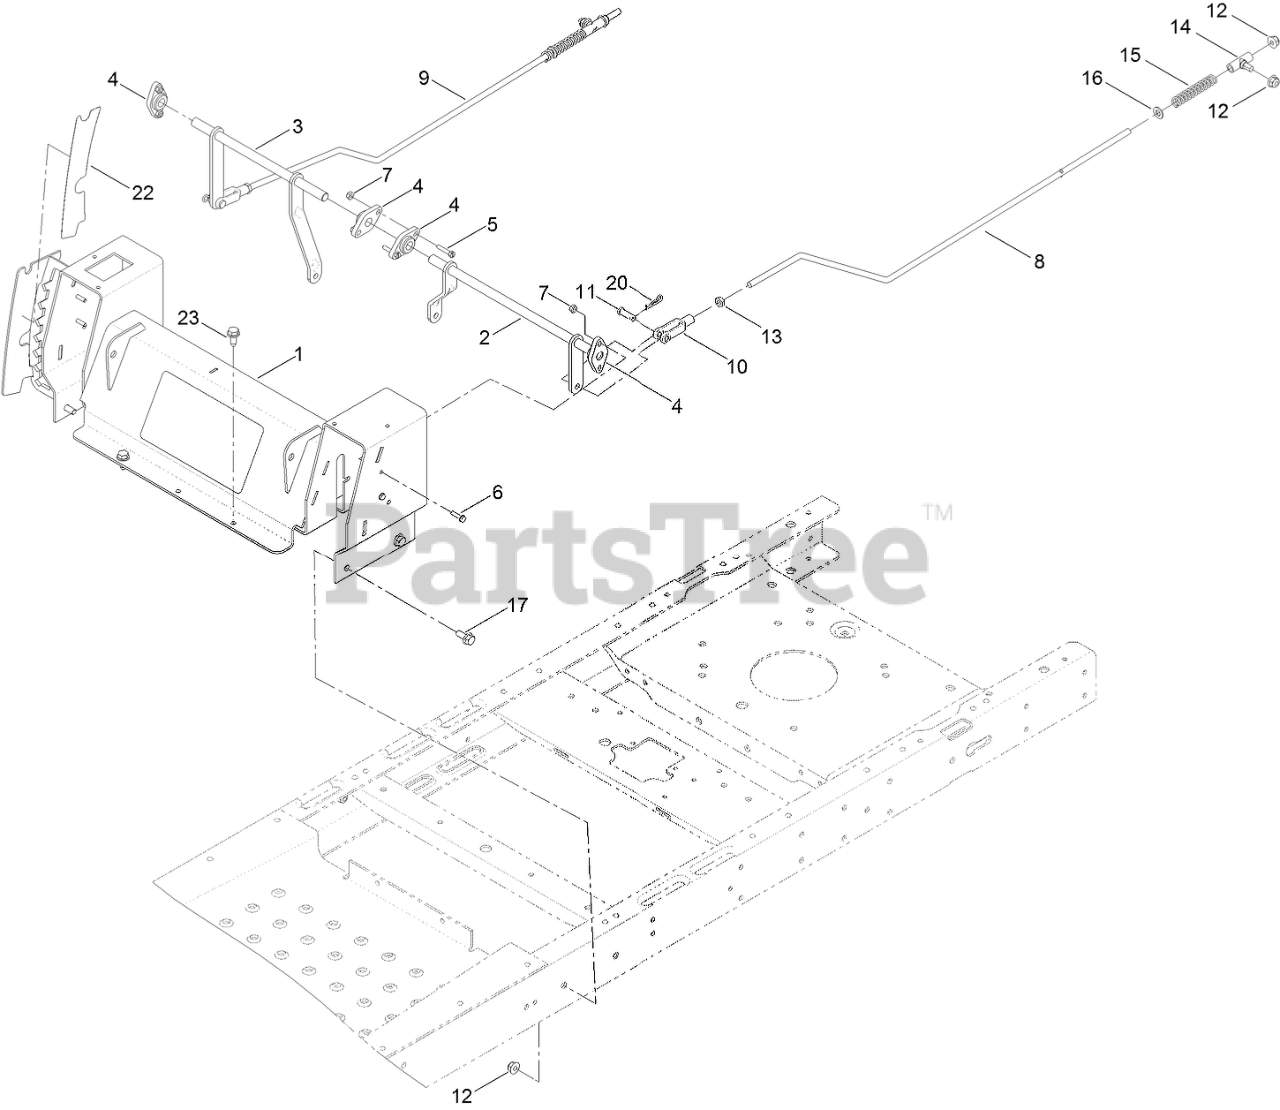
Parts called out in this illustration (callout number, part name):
1	CONTROL BOX ASM
2	BELLCRANK-LH
3	BELLCRANK-RH
4	BEARING-FLANGE
6	SCREW-HWH
7	NUT-LOCK, NI
8	ROD-HYDRO, LH
9	ROD-HYDRO, RH
10	YOKE-ADJUSTABLE
11	PIN-CLEVIS
12	NUT-HF, NI
13	NUT-JAM
14	MOUNT-ROD, HYDRO
15	SPRING-RETURN, NEUTRAL
16	WASHER-PLAIN
17	SCREW-HHF
20	PIN-COTTER
22	DECAL-HOC, CE
23	SCREW-HWHTF
